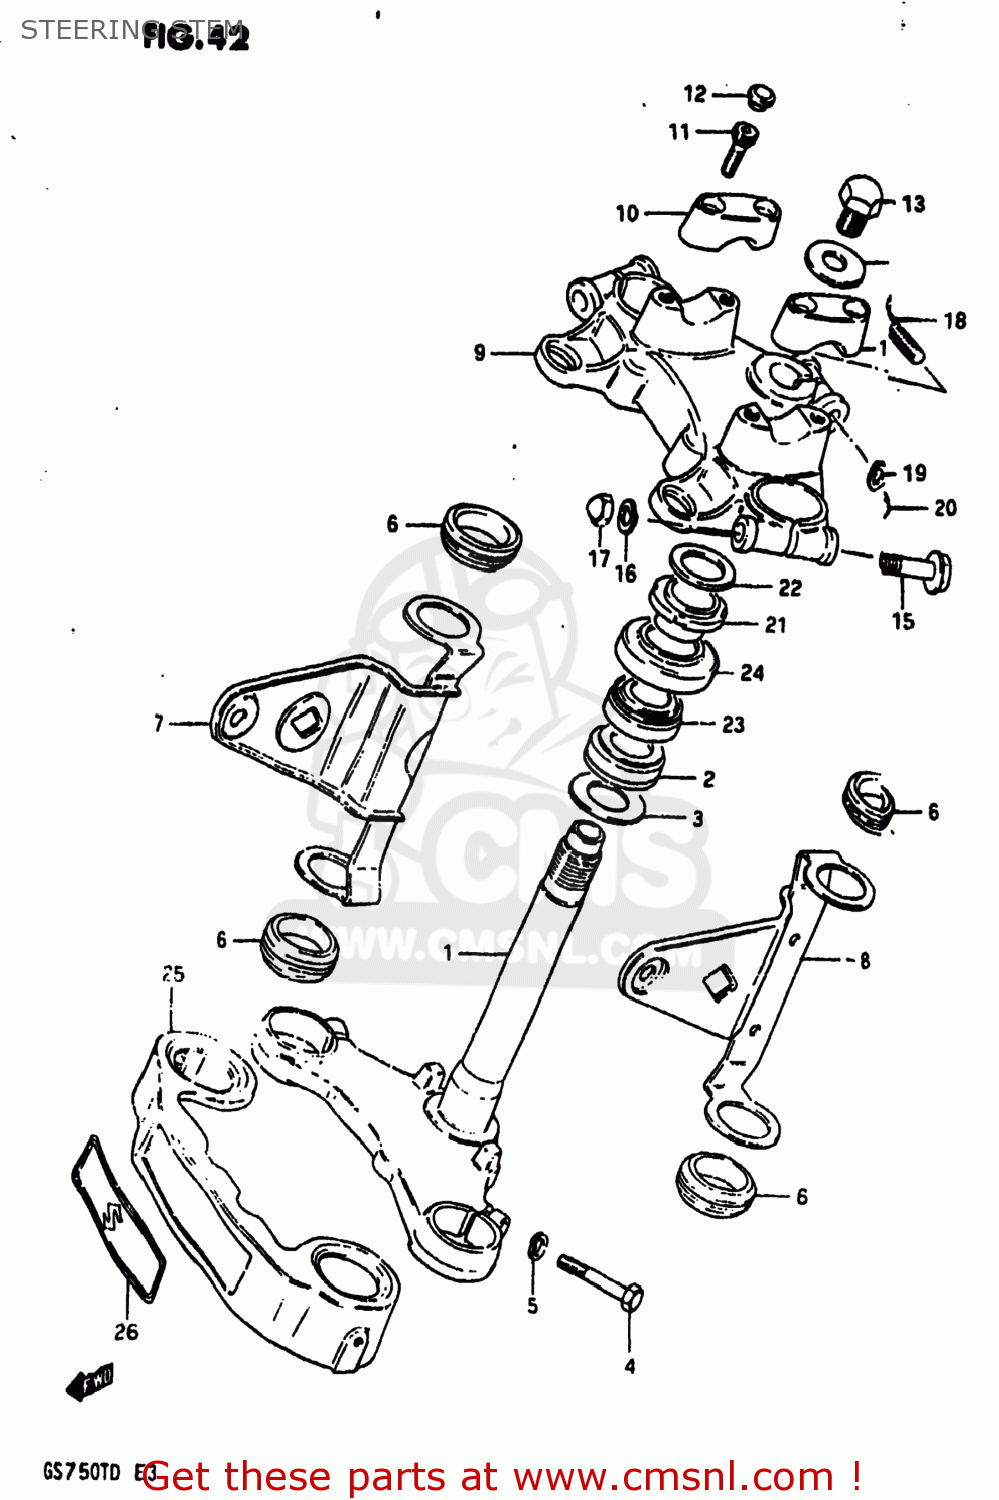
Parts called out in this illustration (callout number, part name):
1	STEM,STEERING
2	BEARING
3	WASHER,THRUST
4	BOLT 10X40
5	LOCK WASHER
6	CUSHION,HEADLAMP BRACKET
7	BRACKET,HEADLAMP,RIGHT
8	BRACKET,HEADLAMP,LEFT
9	HEAD,STEERING STEM
10	HOLDER,HANDLEBAR(BLACK)
11	BOLT
12	CAP(OD:14.5)
13	BOLT(12X20)
14	WASHER
15	BOLT 10X55
16	LOCK WASHER
17	NUT
18	BOLT
19	LOCK WASHER
20	NUT,M8X1.25X12
21	NUT,STEERING STEM
22	WASHER(18.5X24X1)
23	TAPER,ROLLER BEARING
24	DUST SEAL,STEERING UPR
25	COVER,FRONT FORK
26	EMBLEM
